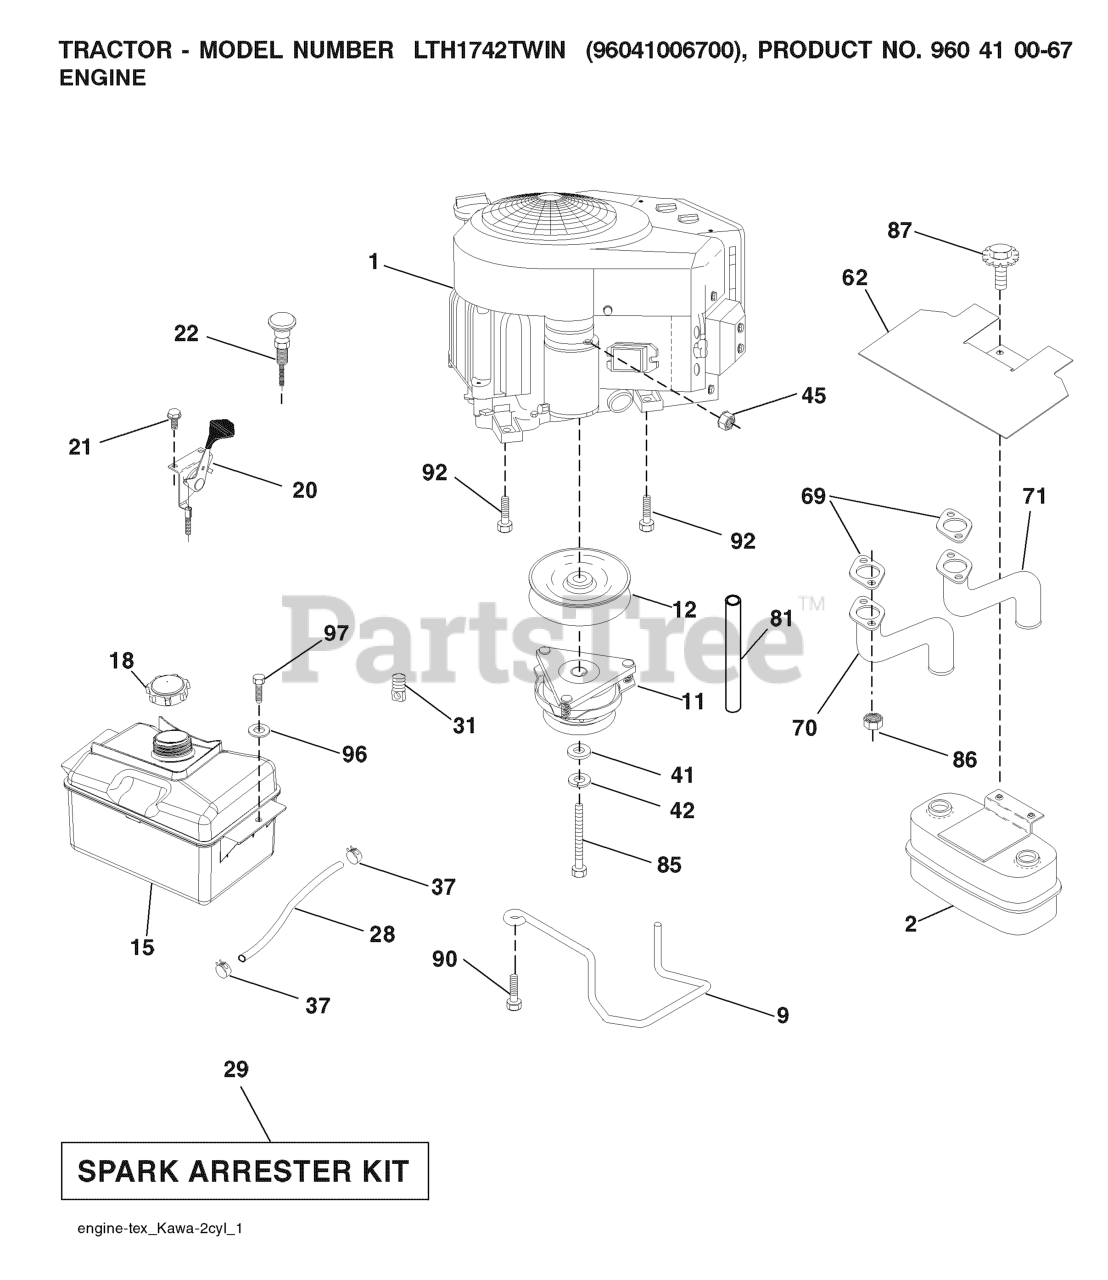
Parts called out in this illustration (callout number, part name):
2	MUFFLER.TWIN.CYL.LOW.TONE
9	KEEPER.BELT.ENGINE.4.2
11	RB.CLUTCH.OGURA.4.4.PD
12	PULLEY.ENGINE.TUFFTORQ
15	RP TANK FUEL FRT 1.5 GAL
18	FUEL CAP
20	THROTTLE CABLE
21	SCREW.#10 X 0.750.BOS
22	CONTROL, CHOKE
28	LINE.FUEL.20
29	KIT.SPARK ARRESTOR 794945 B&S
37	HOSE CLAMP
42	LOCKWASHER
45	NUT
62	RP SHIELD HEAT MUFFLER
70	EXHAUST.TUBE.LH.KAWASAKI.
71	EXHAUST.TUBE.RH.KAWASAKI.
81	TUBE, DRAIN OIL ASM.
85	BOLT HEX 7/16-20X4-1/4"
86	NUT.HEX.FLANGE.TOPLOCK
87	BOLT.5/16-18UNCX3/4 W/SEMS.BLK
90	SCREW 3/8-16X1
92	SCREW 3/8-16X1
97	SCREW HEXWSHR 1/4-20X3/4
